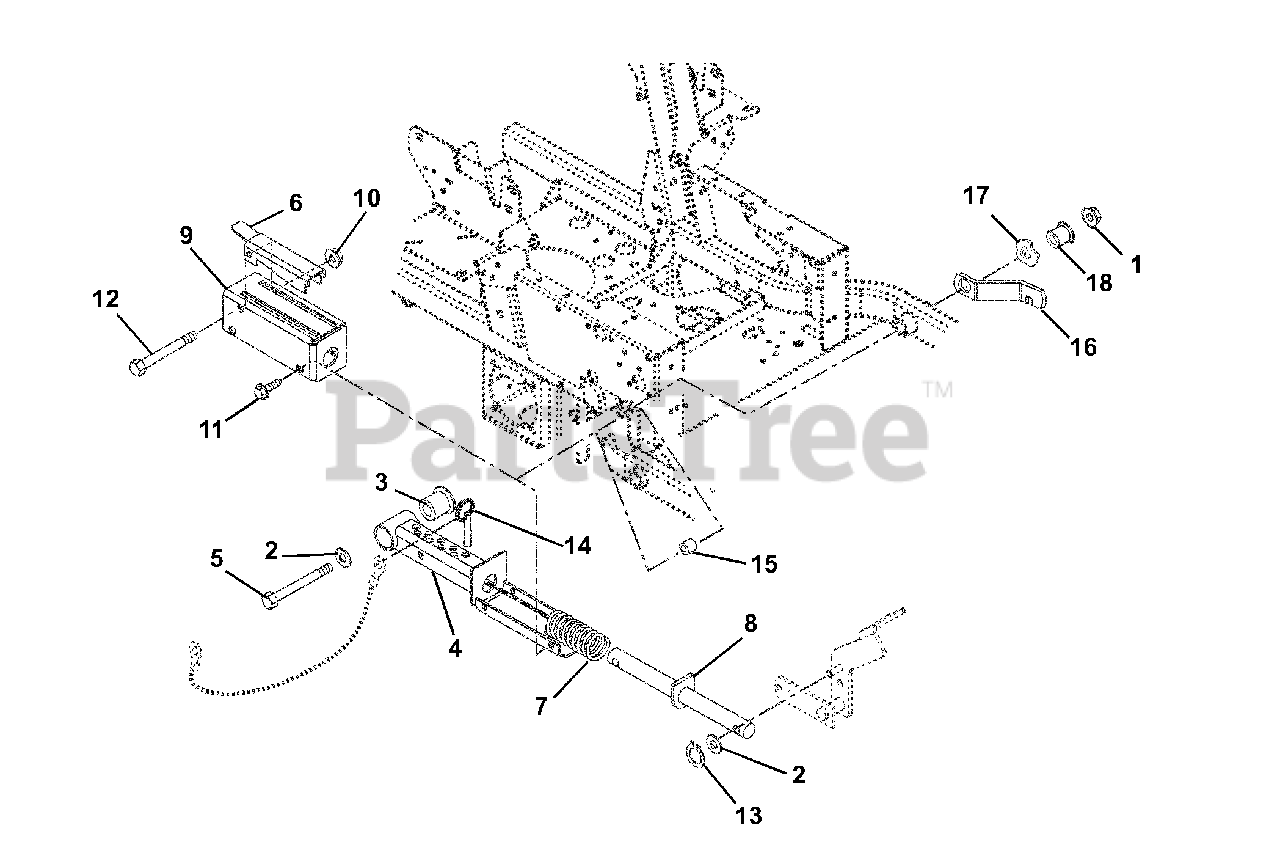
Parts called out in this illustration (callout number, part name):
1	Nut, Locking Top Flange .50-13
2	Washer, Flat Steel .531 x 1.25 x .10
3	Bearing, Pedestal Powdered Metal
4	Weldment, Mechanical Lift
5	Bolt-Hex .50-13 x 5.00 Grade 5
6	Lock-Up, Mechanical Lift
7	Spring, Compression 1.13 x 1.47 x 5.10
8	Weldment, Mechanical Lift Shaft
9	Weldment, Mechanical Lift Cover
10	Nut, Locking Top Flange .38-16
11	Screw, Tapping .38-16 x .50 Hex Washer Head
12	Bolt, Hex .38-16 x 3.25 Grade 5
13	Ring, Retaining External .50 x .05
14	Pin, Spring Ball .375 O.D. x 1.50
15	Spacer .516 ID x 1.000 OD x .875
17	Washer-Wave .076 x 1.120 x .080
18	Bushing-Flange .515 x .750 x .275 x 1.120
